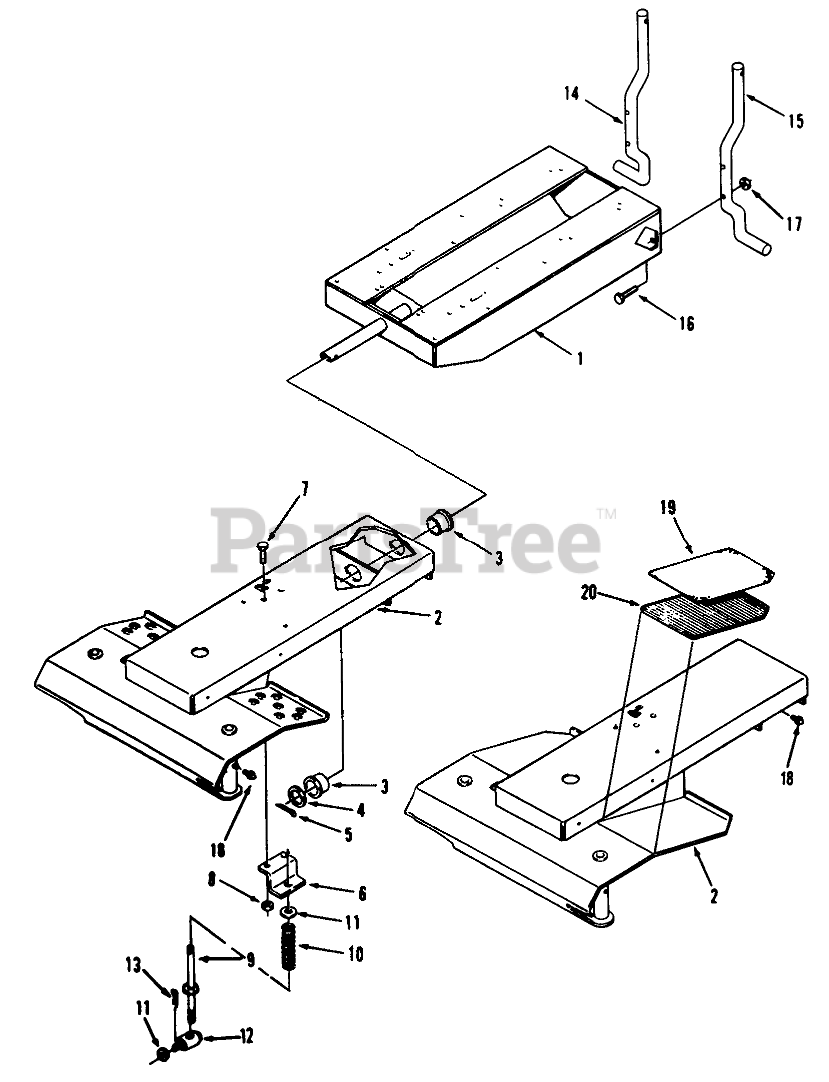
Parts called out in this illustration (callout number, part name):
1	ASS'Y-FRAME REAR R
2	ASSY FRONT FRAME R
3	BEARING FLANGE
4	WASHER
5	Pin-Cotter
6	BRACKET R
7	SCREW-HH
8	NUT-LOCK, NI
9	ASSY ROD
10	SPRING-COMPRESSION
11	WASHER-FLAT
12	TRUNNION
13	PIN-COTTER
14	REAR ROD RH B
15	REAR ROD LH B
16	Bolt
17	LOCKNUT 5/16-18GR.B
18	FITTING-GREASE
19	PAD FOOTREST RH
20	PAD FOOTREST RH
